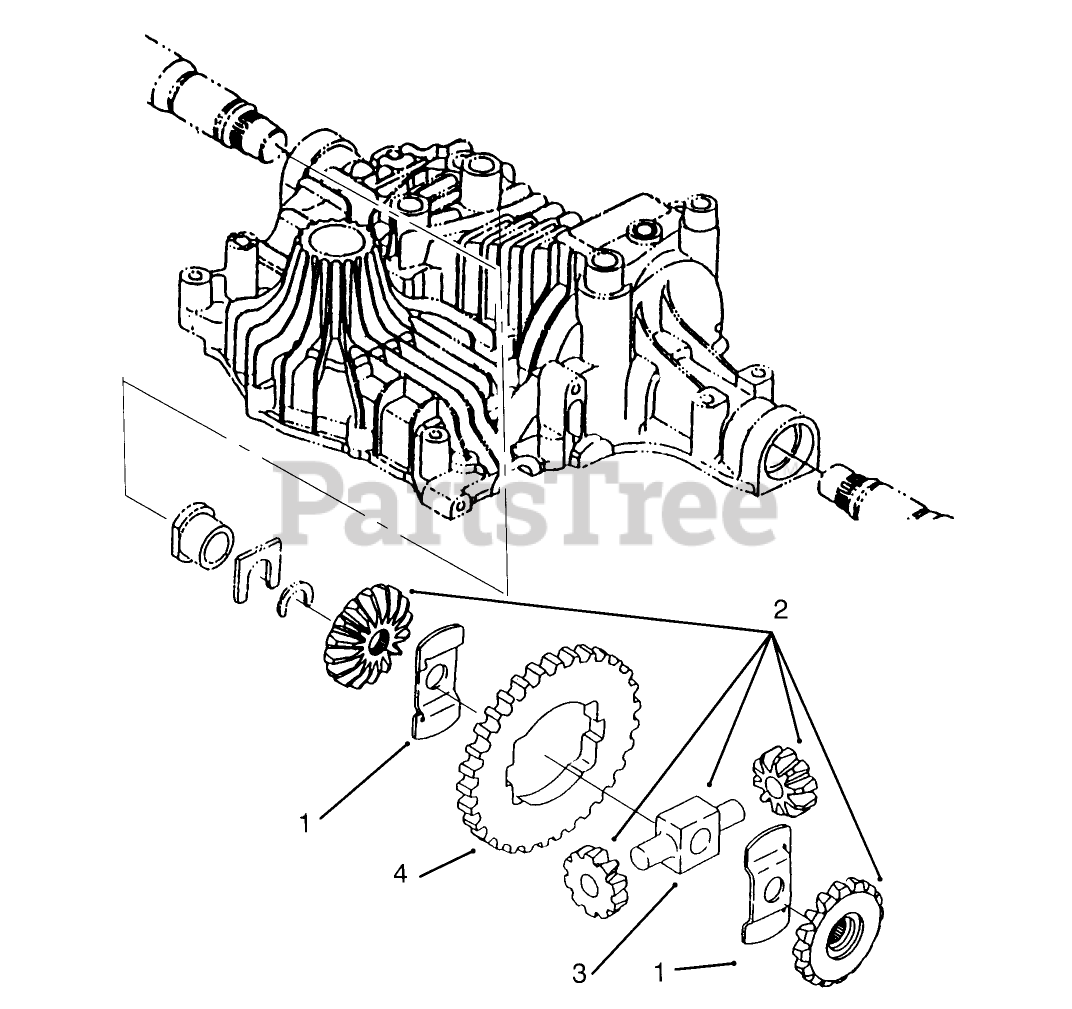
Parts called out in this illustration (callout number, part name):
1	WASHER-THRUST
3	SHAFT - PINION
4	GEAR - FINAL
